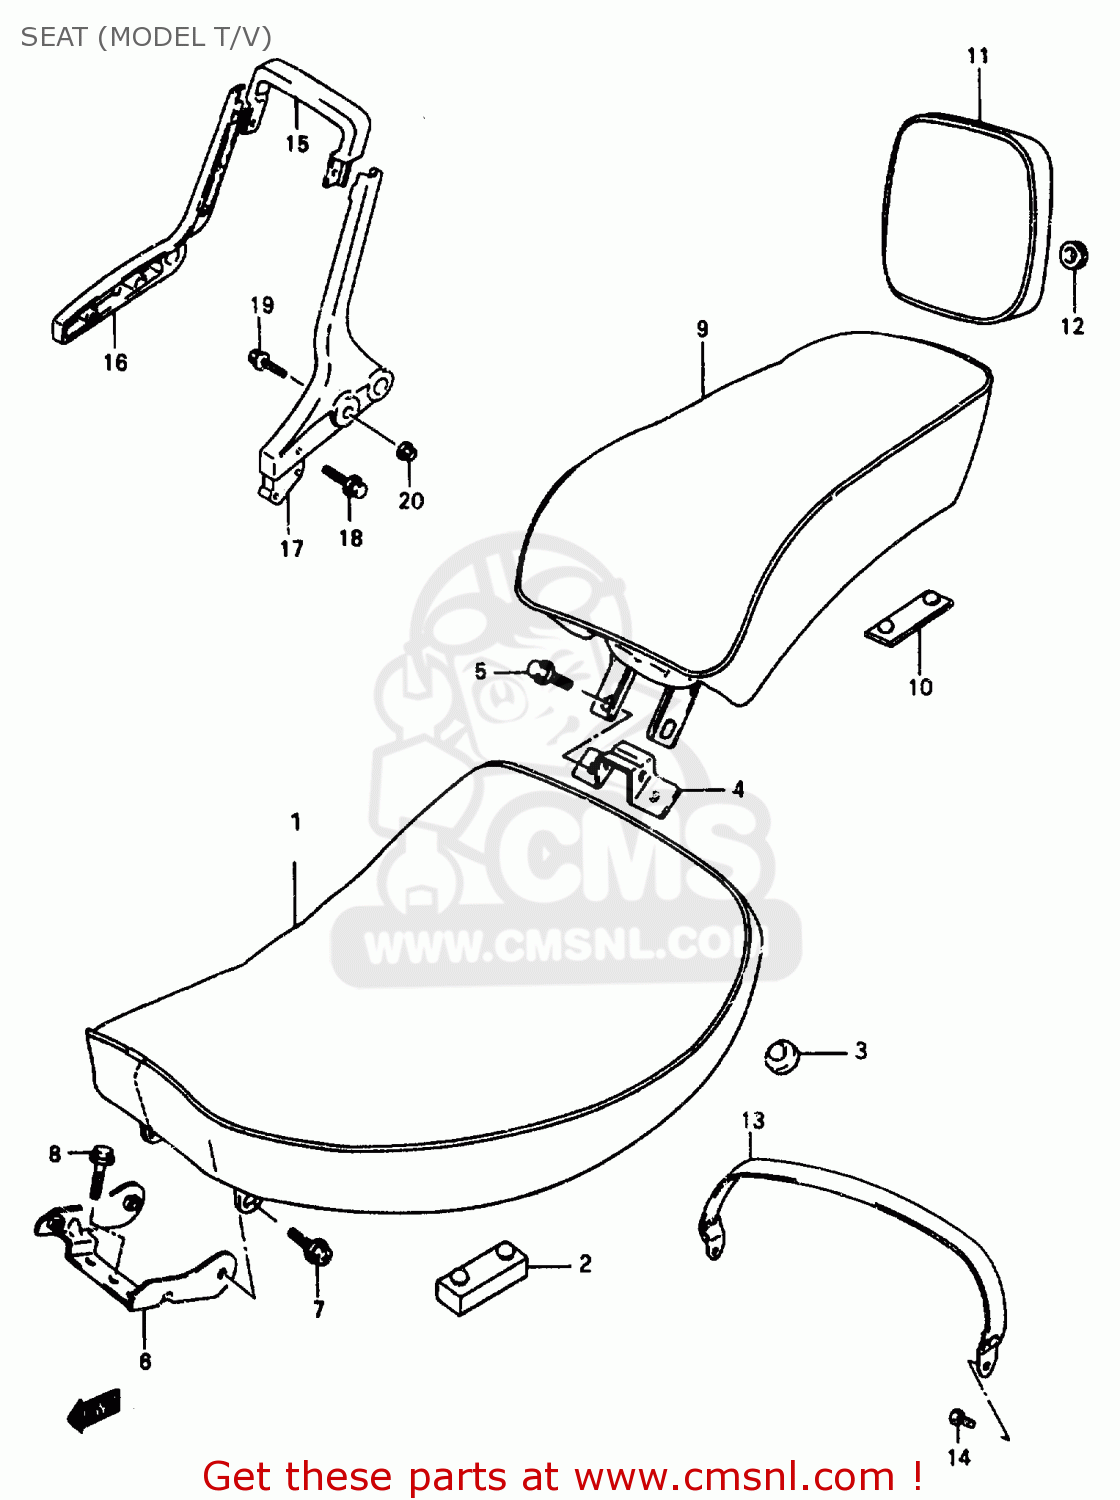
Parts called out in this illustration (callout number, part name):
1	SEAT ASSY
2	CUSHION,SEAT
3	CUSHION
4	PLATE,FR SEAT HOOK & RR
5	BOLT(6X16)
6	BRACKET,SEAT FR
7	BOLT(6X16)
8	BOLT
9	SEAT ASSY,PILLION
10	CUSHION
11	PAD ASSY,SEAT
12	CUSHION
13	BAND, SEAT
14	BOLT
15	HANDLE,PILLION RIDER UPR
16	HANDLE,PILLION RIDER,RIGHT
17	HANDLE,PILLION RIDER,L
18	HANDLE,PILLION RIDER
19	HANDLE,PILLION RIDER
20	NUT
21	BOLT
22	NUT
